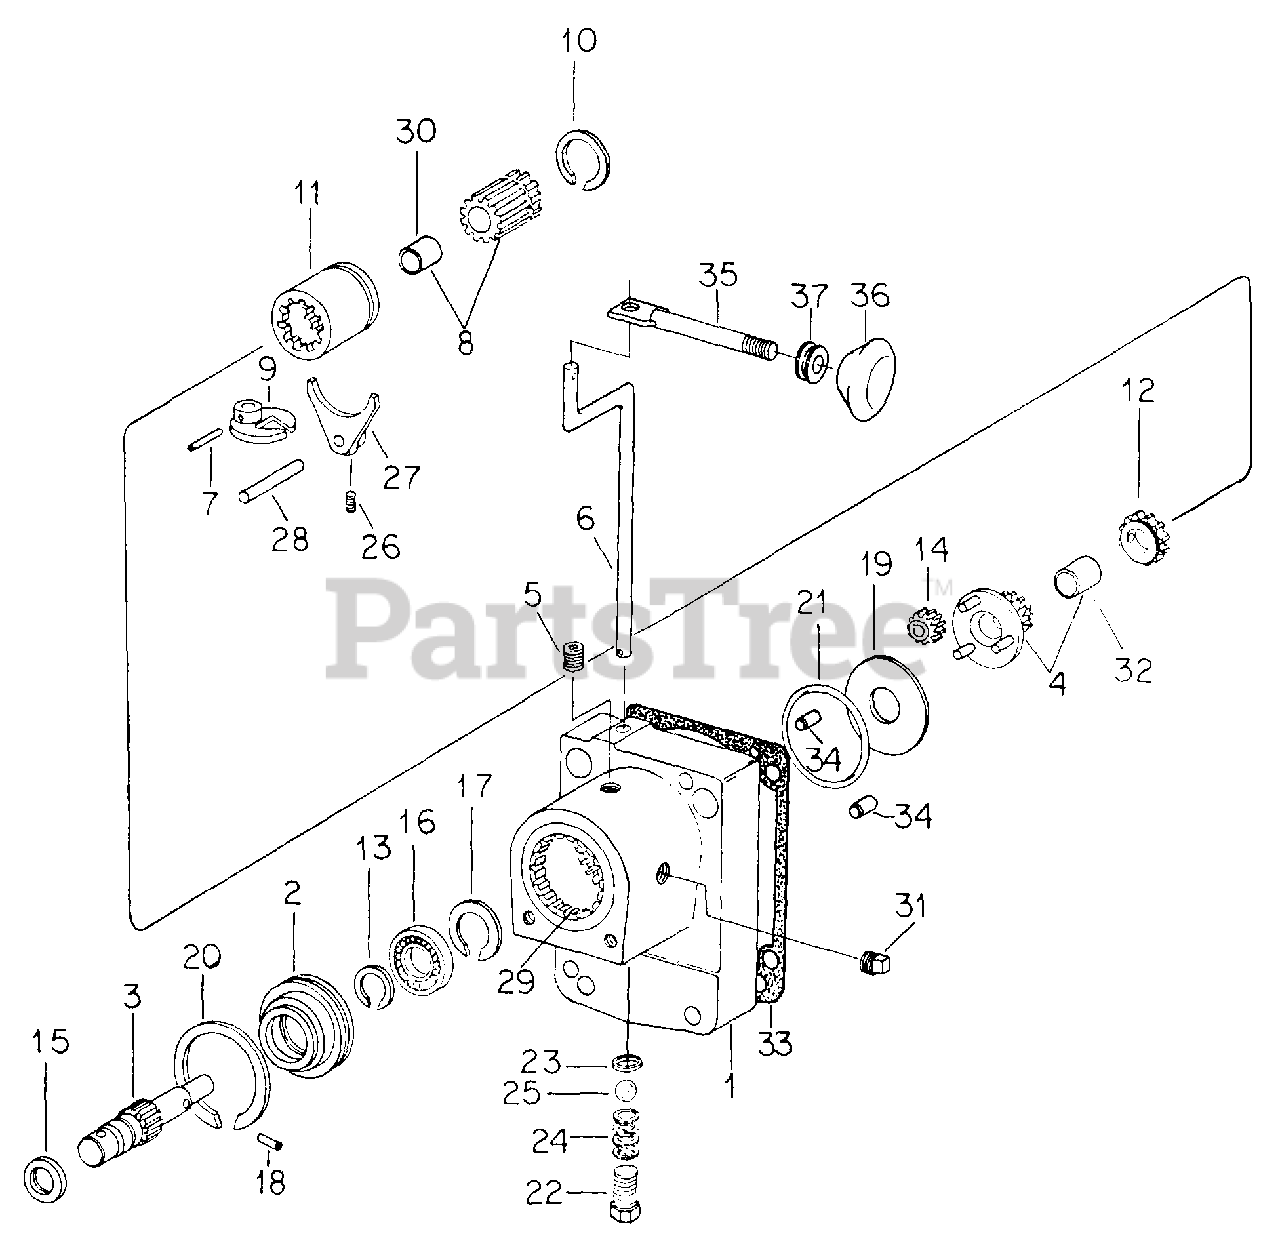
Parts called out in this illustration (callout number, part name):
1	HOUSING ASSY, MAIN GEAR
2	RETAINER, BRG
3	SHAFT, SUN GEAR DRIVE
4	PLATE ASSY, LOW GEAR DRIVE
5	VENT, AIR 1/8-27 PTF -REPLACES PLUG IH-444703
6	LEVER, CONTROL
7	PIN, 5/32 X 7/8 HV COILED SPRING
8	DRIVE W/BUSHING ASSY, GEAR SHAFT SPLINE
9	PLATE, GEAR SHIFT
10	RING, DRIVE GEAR RETAINER
11	SLEEVE, SPINDLE DRIVE
12	GEAR, DIRECT DRIVE SPLINE
13	RING, RETAINING
14	GEAR, PLANET
16	BEARING, BALL
17	RING, RETAINING
18	PIN, 1/4 X 1-1/4 HV COILED SPRING
20	RING, INTERNAL RETAINING
21	O-RING, 2-5/8 X 2-7/8 X 1/8
22	SCREW, 3/8-16 X 1/2 ZND HEX-HD CAP
23	WASHER, 3/8 C-Z MED LOCK
24	SPRING, RETAINER BALL
25	BALL, 9/32 CR-STL
26	SCREW, 1/4-20 X 5/8 HEX-SOC-HD CONE-PT SET
27	FORK, GEAR SHIFT
28	SPINDLE, GEAR SHIFT FORK
29	GEAR, INTERNAL
30	BUSHING, SPLINE DRIVE
31	PLUG, 3/8-18 AUTO SQ-HD PIPE
32	BUSHING, DRIVE PLATE
33	GASKET, REDUCTION GEAR BOX HOUSING
34	PIN, 7/16 X 7/8 DOWEL
35	HANDLE, CREEPER DRIVE CONTROL
36	KNOB, CONTROL HANDLE
37	BUSHING, NYLON SNAP
